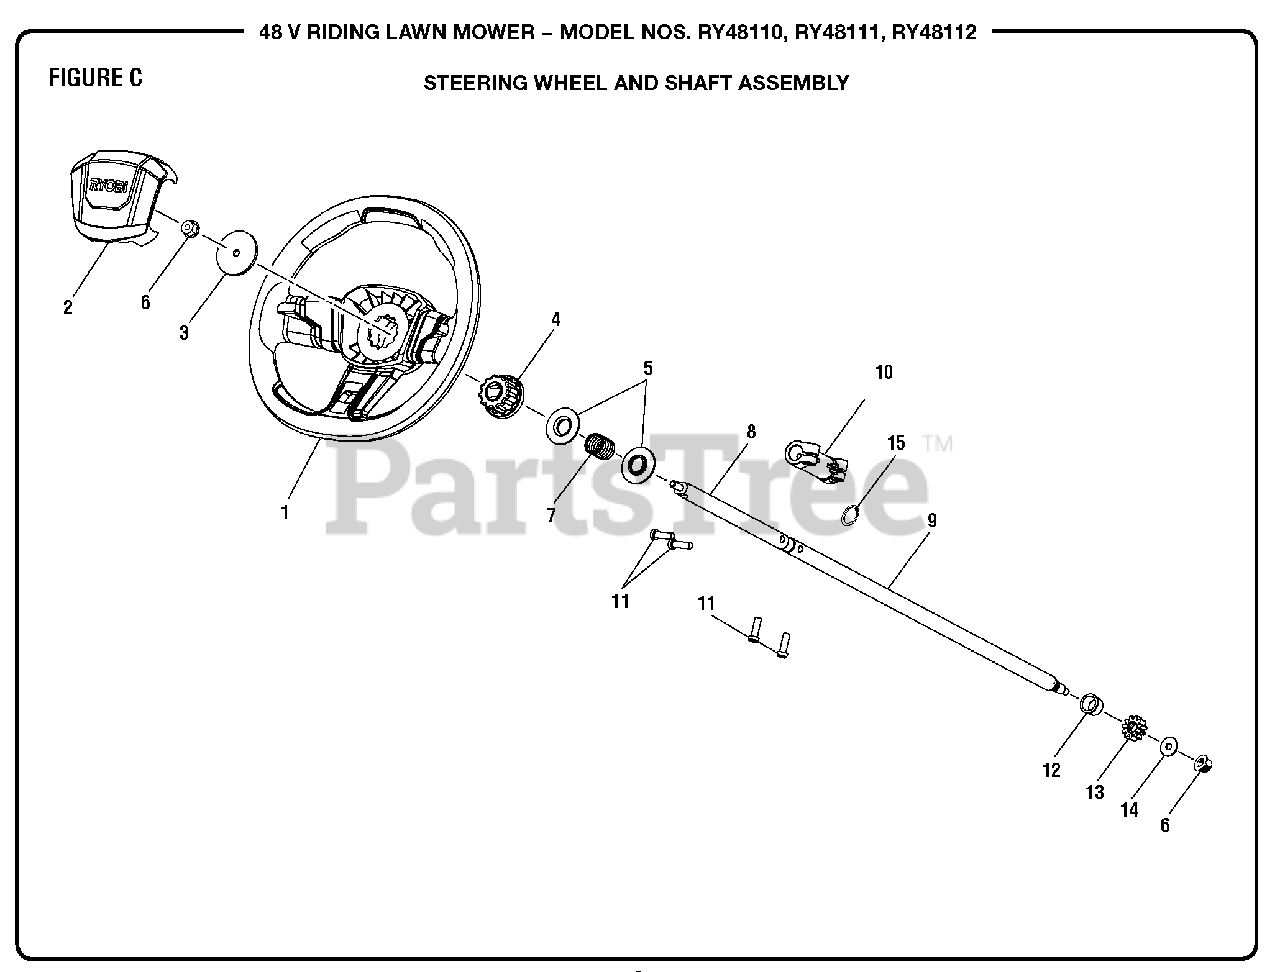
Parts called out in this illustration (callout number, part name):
1	Steering Wheel
2	Steering Wheel Cap
3	Washer Plate
4	Spline Collar
5	Spring Seat
6	Flange Lock Nut (M8)
7	Steering Shaft Spring
8	Upper Steering Shaft
9	Lower Steering Shaft
10	Steering Shaft Coupling
11	Screw (M8 x 25 mm, Soc. Hd.)
12	Flanged Bushing (19 x 22 x 15)
13	Steering Pinion Gear
14	Washer (OD24 x ID8.4 x 2t)
15	Retaining Ring
